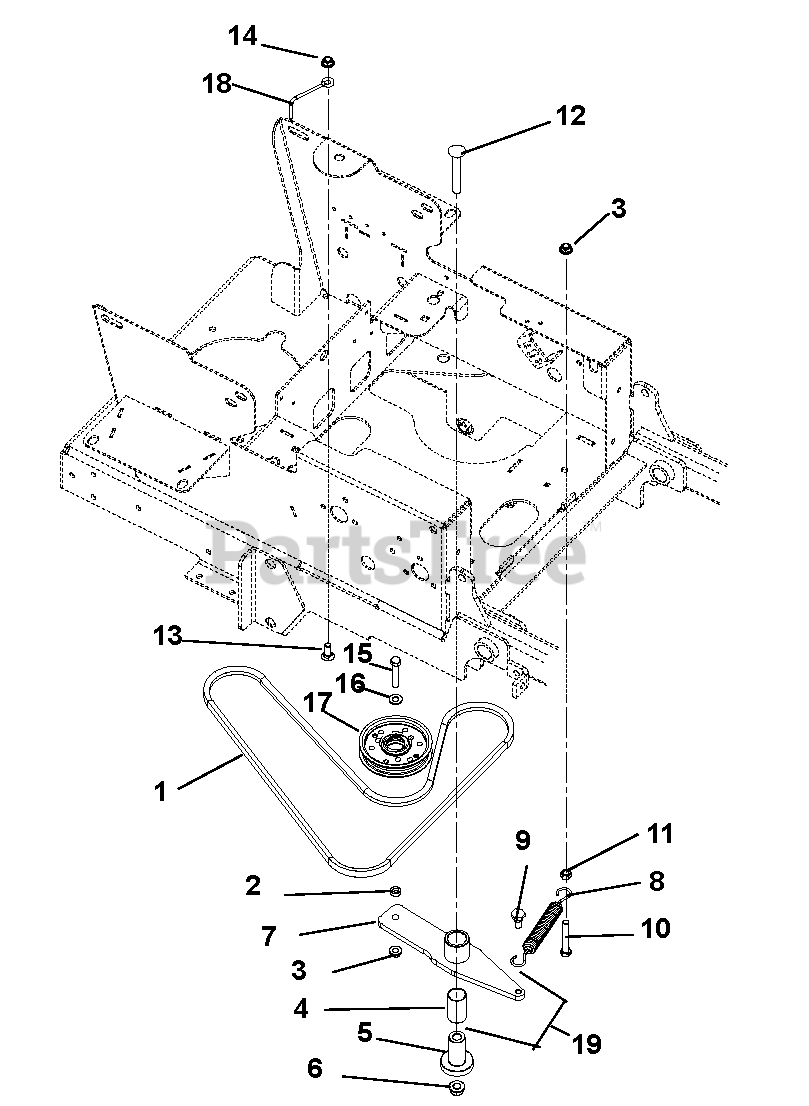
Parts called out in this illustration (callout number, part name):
1	Belt, 4L 67.47 Wrapped
2	Bushing, Sleeve .377 x .624 x .235
3	Nut, .38-16 Nyloc Flange
4	Bushing, 1.00 x 1.125 x 1.936
5	Bearing, Pedestal
6	Nut .50-13 Nyloc Flange
7	Weldment, Hydro Drive Idler Arm
8	Spring, Extension
9	Bolt, Shoulder EP .38-16 x .30 Hex
10	Bolt, Hex .38-16 x 2.50 Grade 5
11	Nut, Locking-Center .375-16
12	Bolt, Round Head Square Neck .50-13 x 3.50
13	Bolt, Round Head Square Neck .38-16 x 1.00 Grade 5
14	Nut, .38-16 Nyloc Flange
15	Bolt, Hex .38-16 x 2.00 Grade 5
16	Washer, Flat-Steel .406 x .812 x .065
17	Assembly, 4" Idler
18	Belt Finger
19	Assembly, Ground Drive Idler (Includes item 4 and 7)
